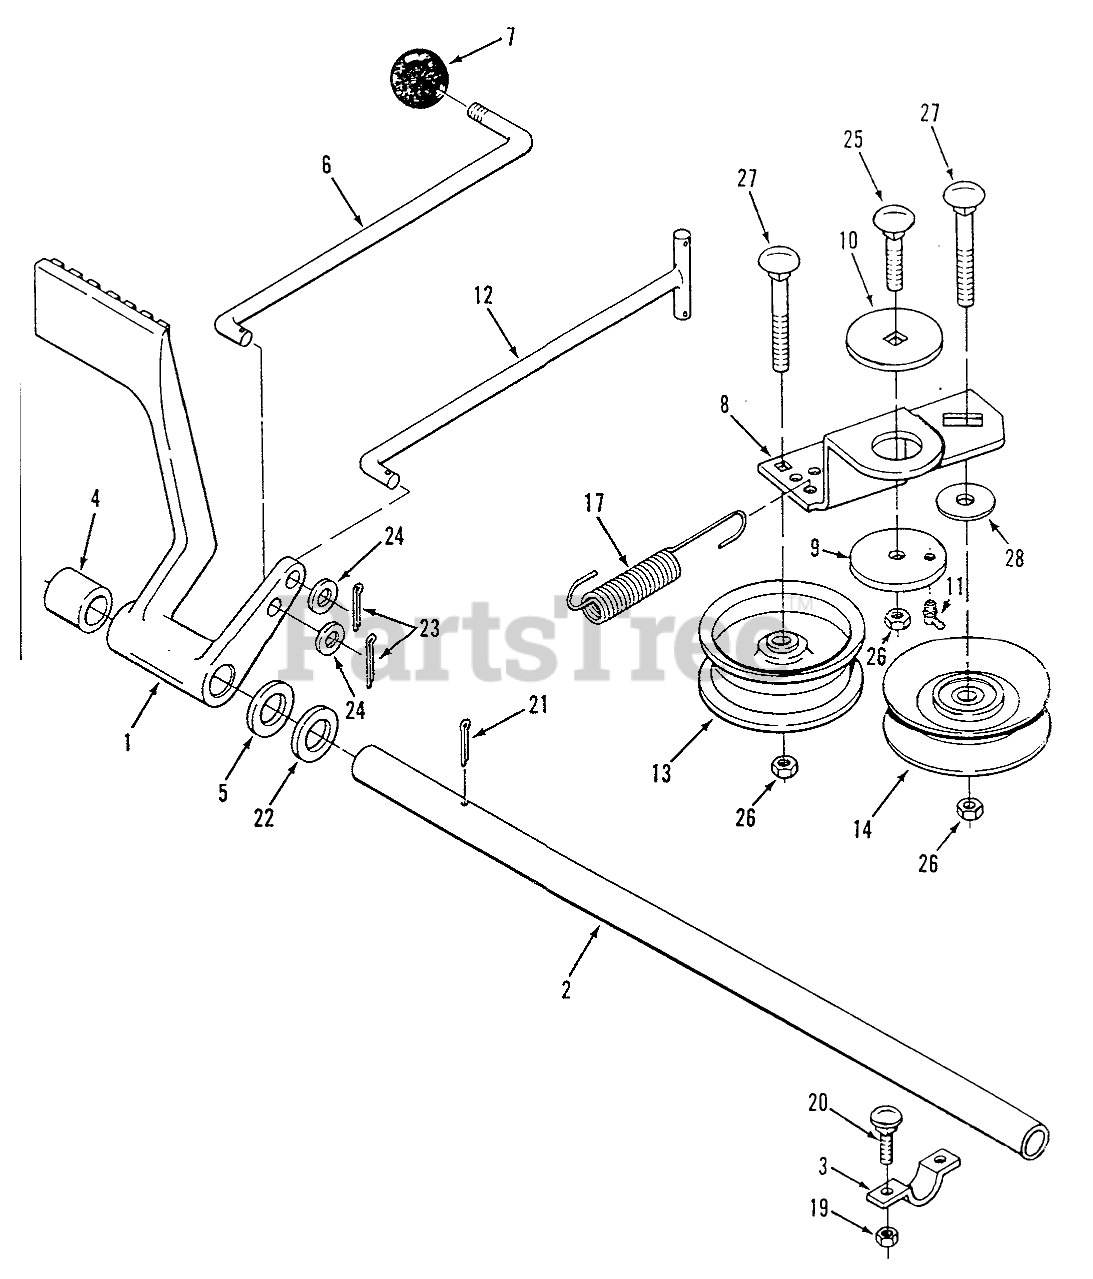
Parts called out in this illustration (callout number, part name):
1	PEDAL-BRAKE R
2	SHAFT PEDAL
3	CLAMP
4	SPACER
5	WASHER-WAVE
6	ROD-BRAKE LOCK B
7	KNOB
8	ARM-IDLER R
9	BUSHING
10	WASHER-BEARING
11	Fitting-Grease
12	ASSY-ROD FRONT BR
13	PULLEY IDLER
14	PULLEY-IDLER
17	SPRING
19	Nut
20	Bolt
22	Washer
23	Cotter Pin
24	WASHER 5/16 SAE
25	Bolt
26	NUT
27	Carriage Bolt 3/8-16 x 1-3/4
28	Washer
